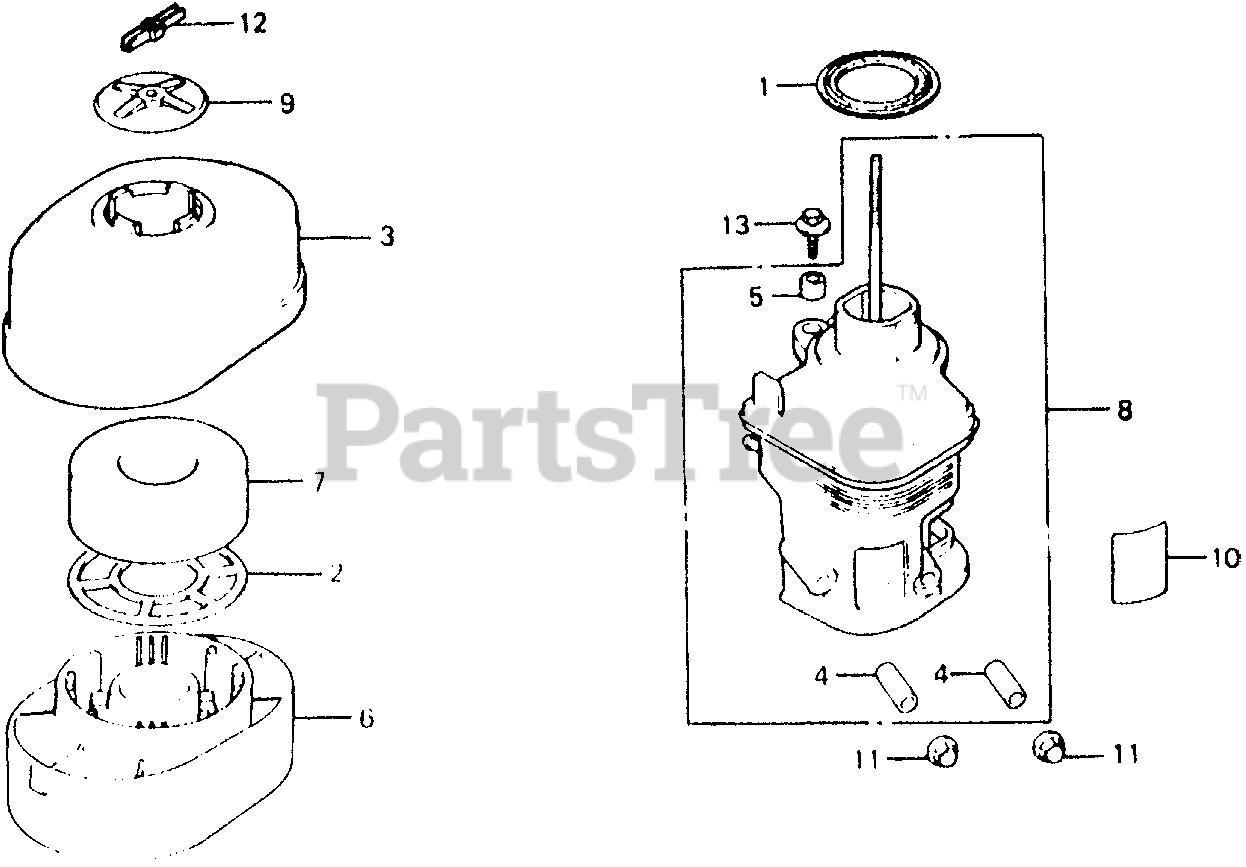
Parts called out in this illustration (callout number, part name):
1	GASKET, ELBOW
2	GRID, AIR CLEANER (OIL BATH)
3	COVER, AIR CLEANER (OIL BATH)
4	COLLAR, AIR CLEANER
5	COLLAR B, AIR CLEANER
6	PAN, CLEANER OIL (OIL BATH)
7	ELEMENT, AIR CLEANER (OIL BATH)
8	ELBOW, AIR CLEANER
9	CAP, AIR CLEANER
10	MARK, CHOKE (EXTERNAL)
11	NUT, CAP (6MM)
12	WINGNUT, AIR CLEANER COVER
13	BOLT-WASHER (6X20)
